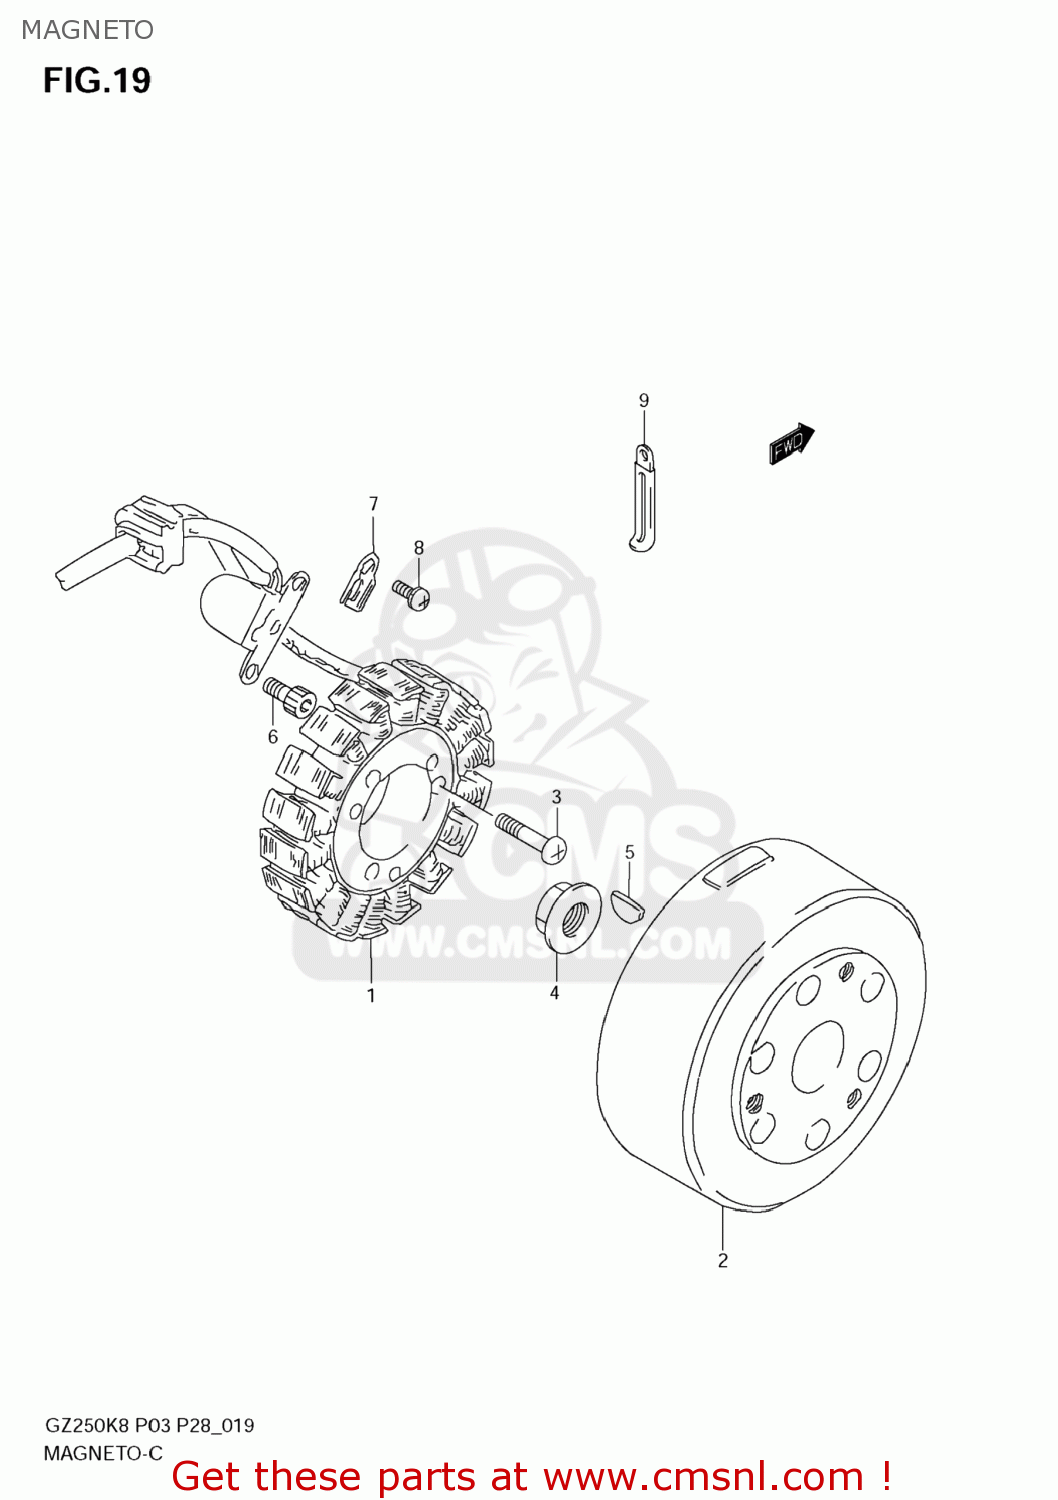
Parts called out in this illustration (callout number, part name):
1	STARTER ASSY
2	ROTOR ASSY
3	SCREW
4	NUT,GENERATOR ROTOR
5	KEY
6	BOLT
7	CLAMP,GENERATOR LEAD WIRE
8	SCREW
9	CLAMP(L:45)
